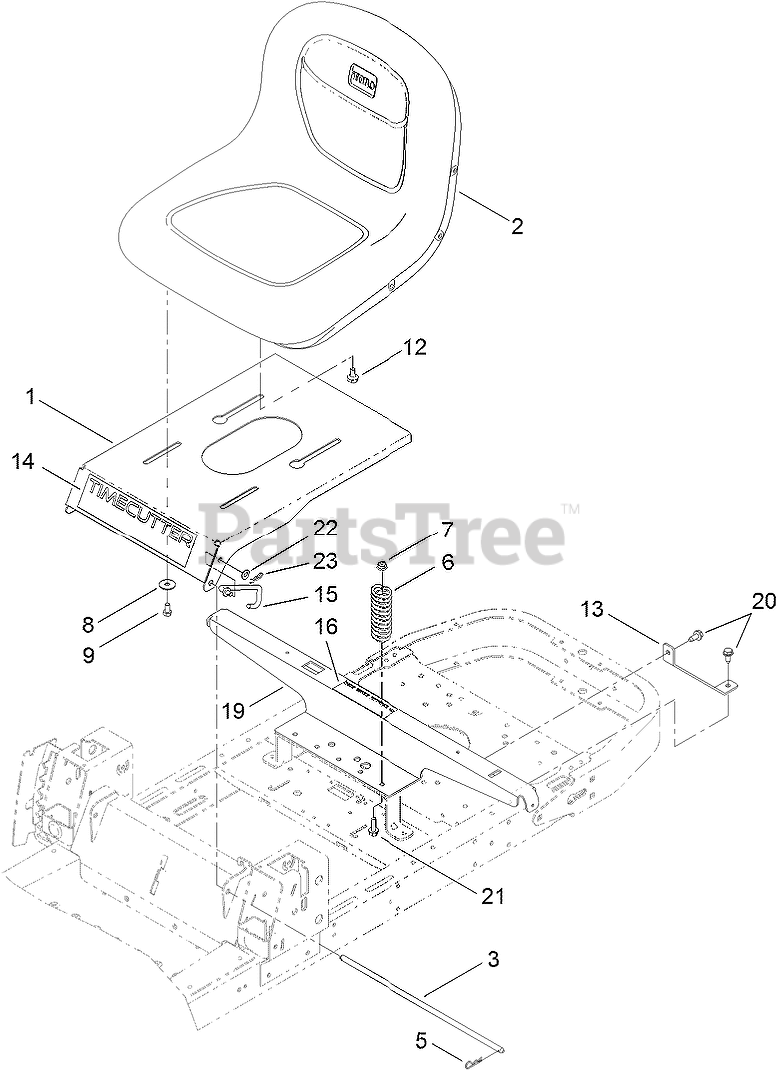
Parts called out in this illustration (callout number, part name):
1	PAN-SEAT
2	SEAT-15 INCH
3	ROD-PIVOT, NARROW
5	PIN-COTTER
6	SPRING-COMPRESSION
7	NUT-HF, NI
8	WASHER-PIVOT
9	SCREW-HH
12	BOLT-SHOULDER
13	SUPPORT-TANK, REAR
14	DECAL-TIMECUTTER
15	STOP-SEAT
16	DECAL-SERVICE, CE
19	SUPPORT-POD
20	SCREW-HWHTF
21	SCREW-HHF
22	WASHER-PLAIN
23	PIN-COTTER
